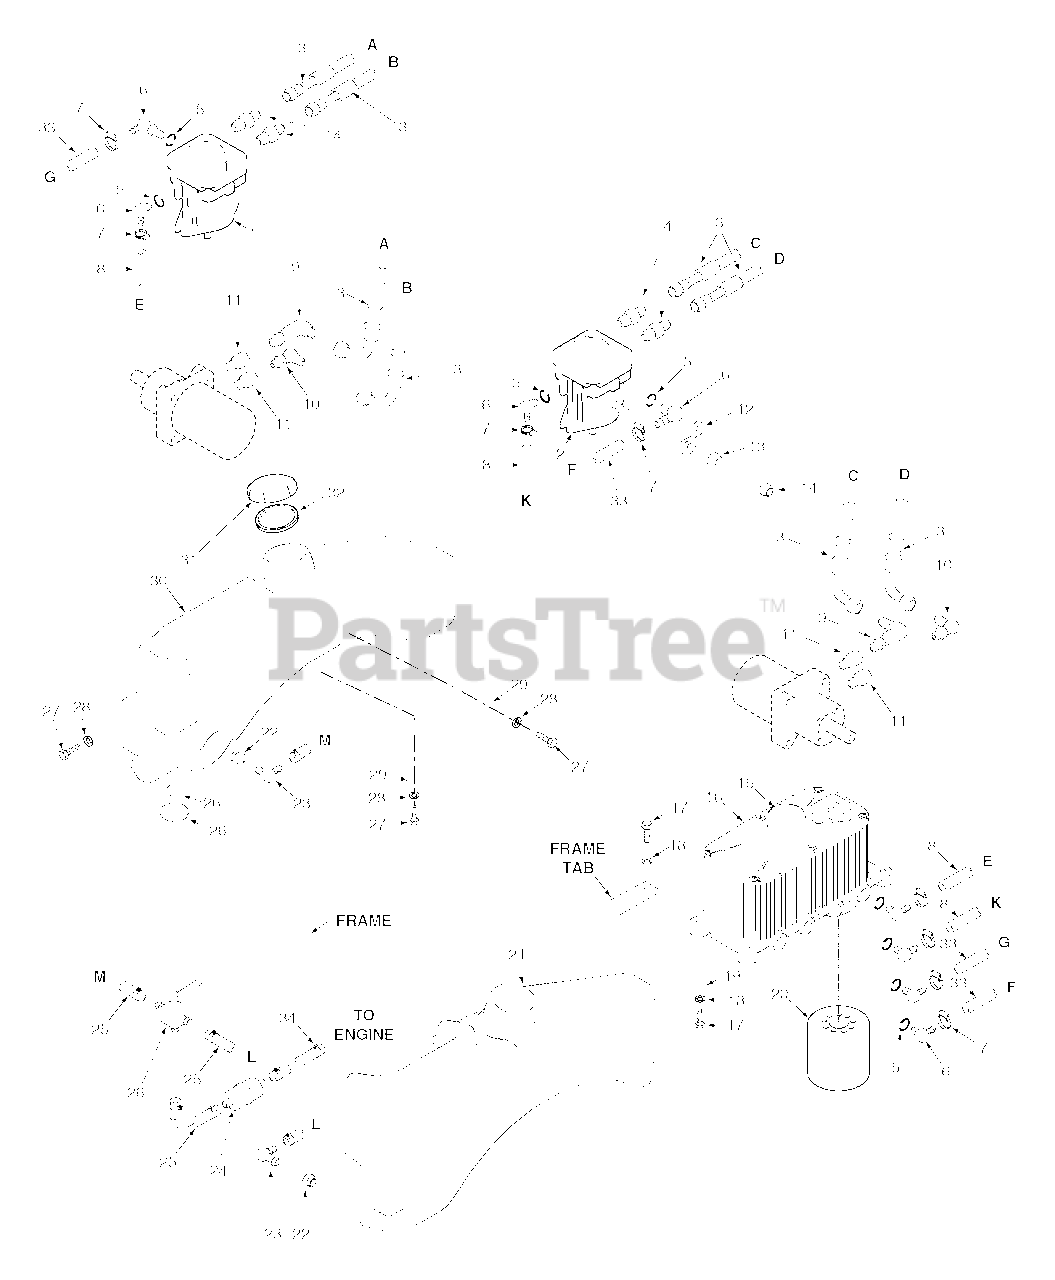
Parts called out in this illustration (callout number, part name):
1	Pump, R.H. BDP-10A (PG-1GCC-D11X-XXXX)
2	Pump, L.H. BDP-10A (PG-1JCC-D11X-XXXX)
3	Hose Assembly, Wheel Motor SZC
4	Fitting, 1/2" JIC x 1/2" O-Ring
5	O-Ring
6	Elbow, 90 Degree O-Ring 9/16-18 x 3/8 Hose
7	Clamp, Hose .69 Max Dia.
8	Hose, 3/8" Pushlock (order by inch)
9	Elbow, 90 Degree JIC to O-Ring
10	Elbow, 90 Degree 1/2 x 1/2" JIC to O-Ring
11	O-Ring Bushing, 5/8"
12	Control Lever, Pump
13	Retainer, Pump Lever
14	Nut, Center Lock 5/16-24
15	Cap, Oil Reservoir
16	Oil Reservoir
17	Bolt, Hex Head 5/16-18 x 1"
18	Lockwasher, 5/16" Spring
19	Flatwasher, 5/16-.375 x .875 x .083
20	Filter, Spin On
21	Fuel Tank, L.H. SZC
22	Tank Bushing
23	Elbow, 90 Degree
24	Fuel Filter
25	Fuel Hose, 1/4 ID
26	Valve, Fuel Shutoff
27	Bolt, Hex Head 5/16-18 x 3/4"
28	Lockwasher, 5/16
29	Flatwasher, 5/16-.375 x .875 x .083
30	Fuel Tank, R.H. SZC
31	Cap, Fuel Tank
32	Gasket, Gas Tank Cap
33	Hose, 3/8" Pushlock Gray (order by inch)
34	Clamp, Fuel Hose 1/4 Hose ID
